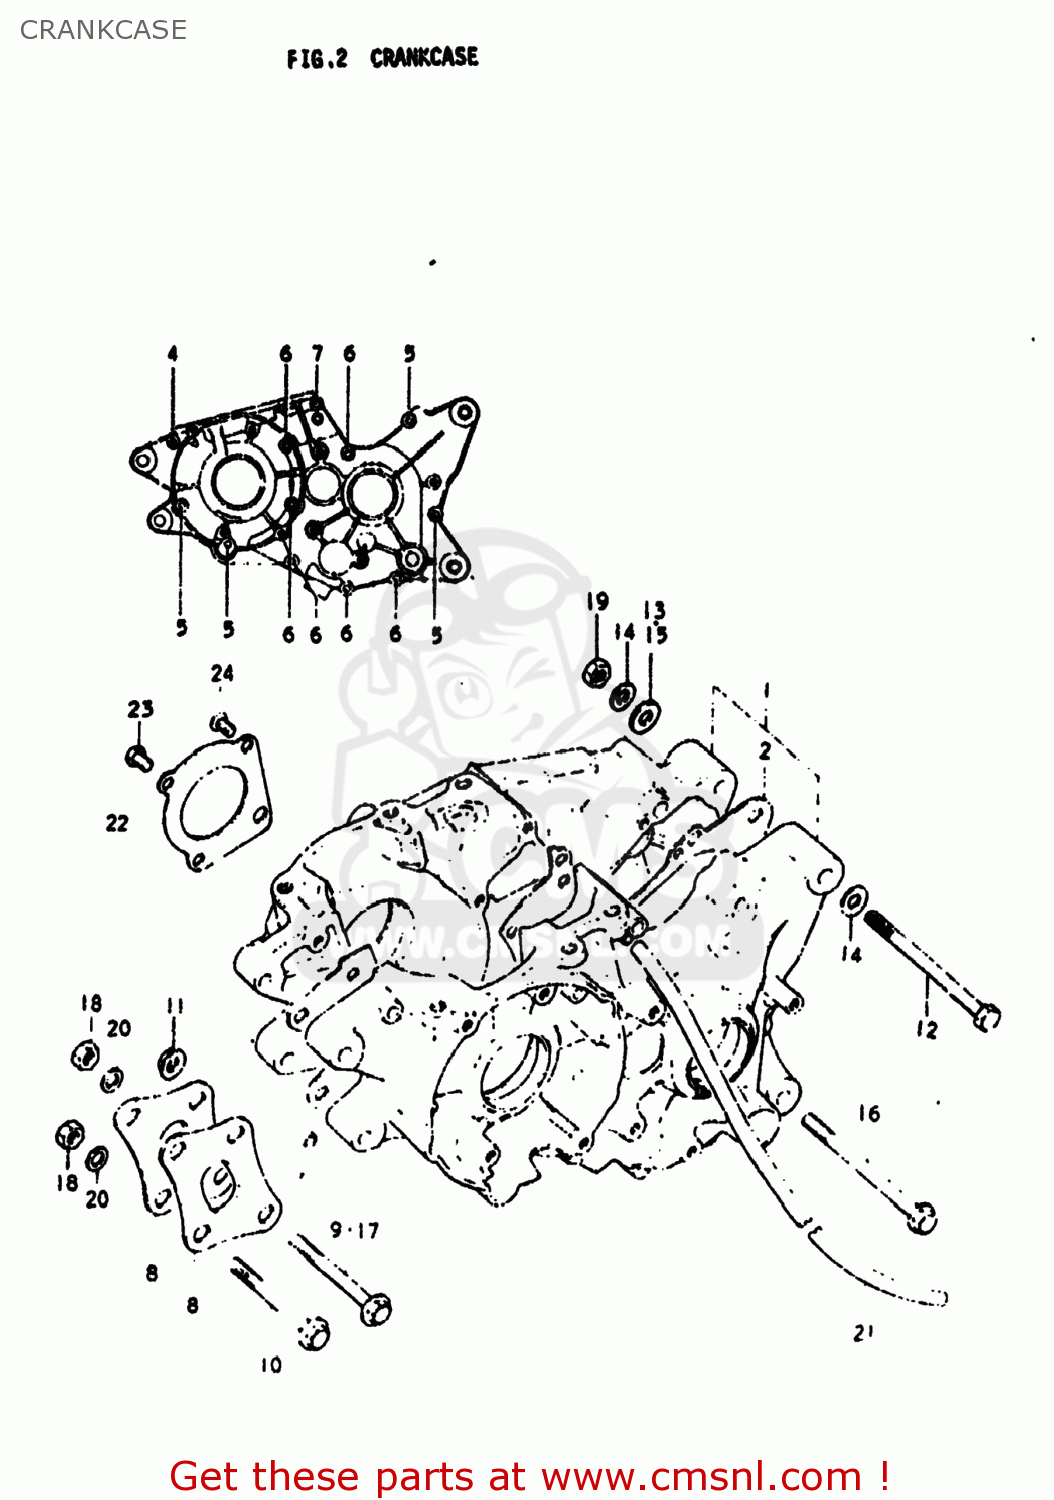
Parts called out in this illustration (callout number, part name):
1	CRANKCASE SET
2	GASKET,CRANKCASE
3	PIN
4	SCREW (6X35)
5	SCREW (6X45)
6	SCREW
7	SCREW 6X65
8	PLATE,ENGINE MOUNTING
9	BOLT (8X70)
10	BOLT 8X75
11	NUT
12	BOLT(10X110)
13	WASHER
14	WASHER
15	WASHER
16	BOLT
17	BOLT (8X70)
18	NUT
19	NUT
20	WASHER
21	HOSE
22	PLATE,OIL RESERVOIR
23	SCREW 6X12
24	SCREW
